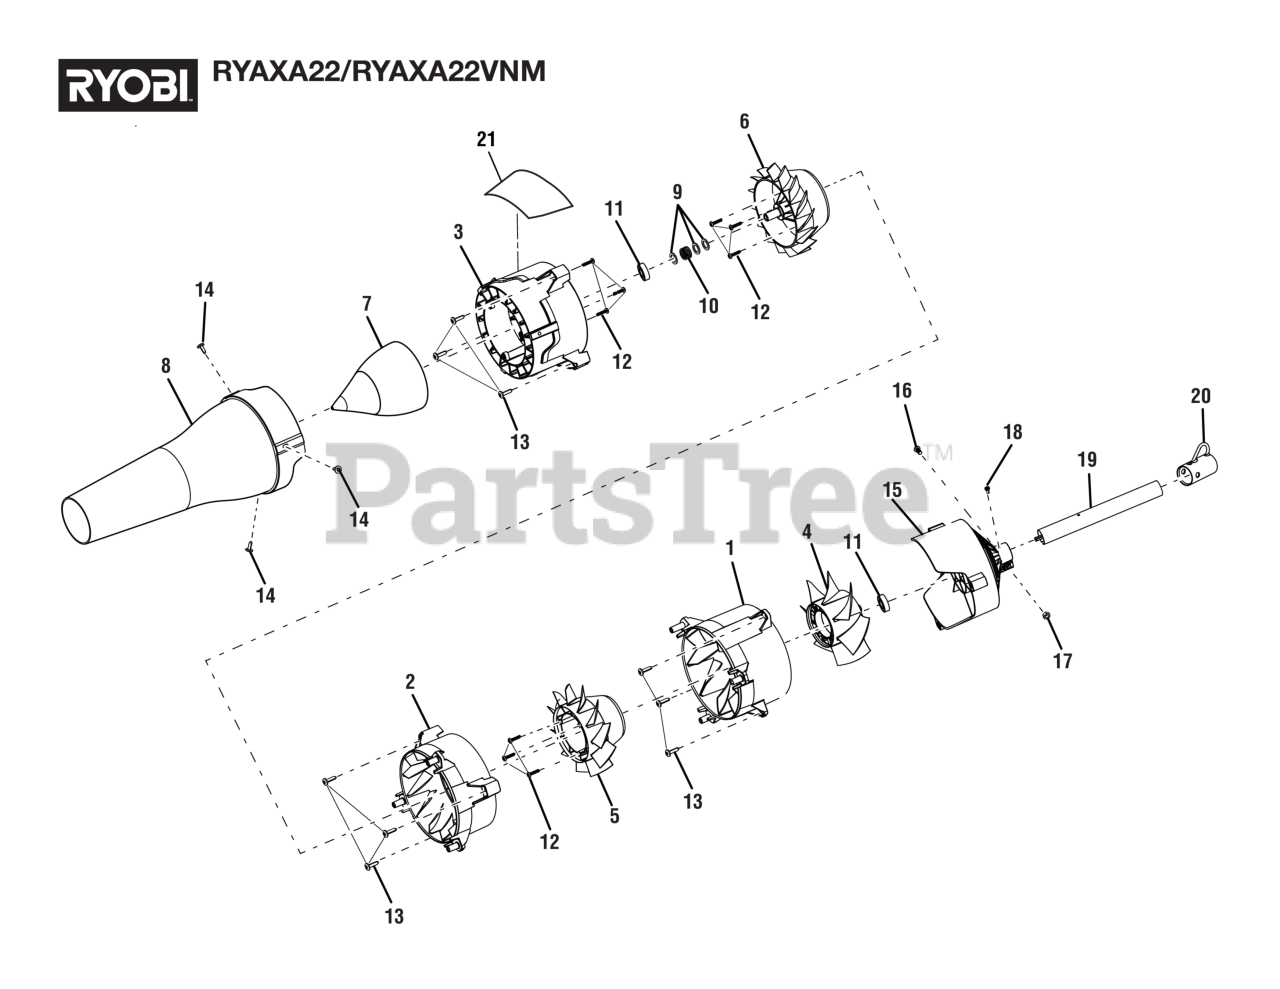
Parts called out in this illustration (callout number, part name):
1	Axial Stator (Stage One)
2	Axial Stator (Stage Two)
3	Axial Stator (Stage Three, Inc. Key No. 21)
4	Axial Fan (Stage One)
5	Axial Fan (Stage Two)
6	Axial Fan (Stage Three)
7	Reducer Cone
8	Reducer Nozzle
9	Washer (OD18 x ID12.15 x 1.5t)
10	Wavy Spring (ID6.51 x HGT9.52)
11	Ball Bearing (6001-zz)
12	Screw (M4 x 1.41 mm x 18 mm, T20 Torx Pan Hd. T.F)
13	Screw (10-14 x 19 mm, T25 Torx Truss Pan Hd. T.F.)
14	Vacuum Tube Screw (10-14 x 1/2 in., T25 Torx Truss Hd. T.F.)
16	Screw (M6 x 12 mm, T27 Torx Pan Hd.)
17	Hex Nut (M6.3 x 1)
18	Screw (M4 x 8 mm, T25 Torx Pan Hd. T.F.)
19	Boom Assembly
20	Hanger Cap
21	Safety Icon Label
